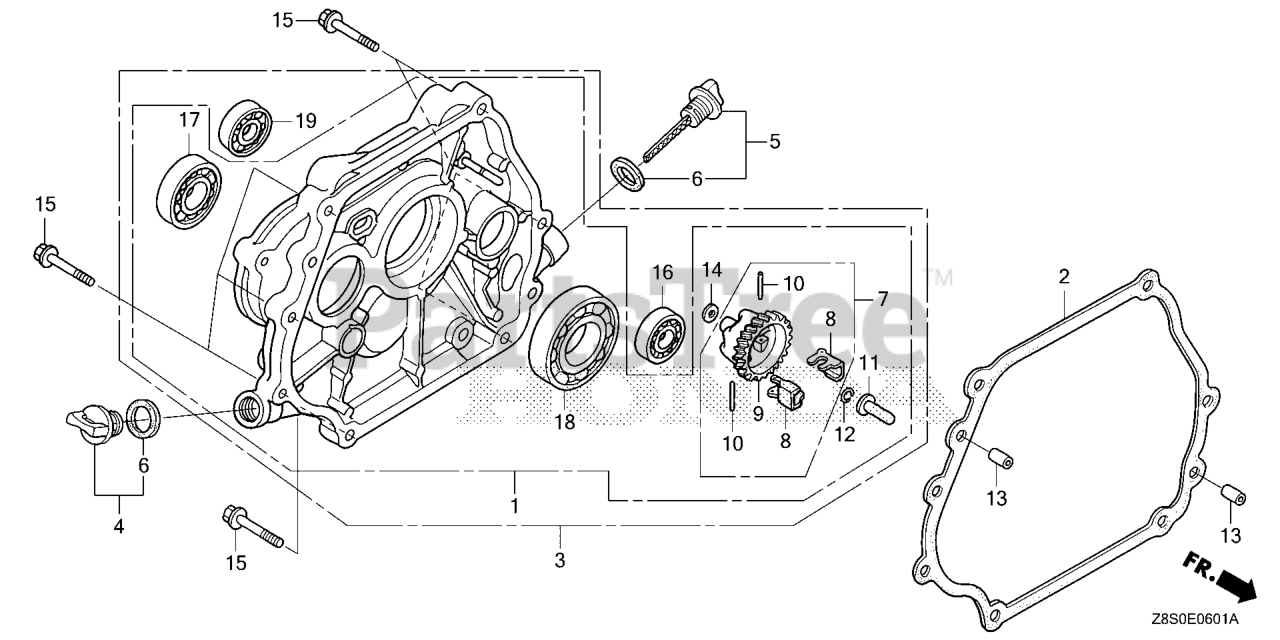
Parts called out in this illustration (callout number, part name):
2	GASKET, CASE COVER
3	COVER ASSY., CRANKCASE
4	CAP ASSY., OIL FILLER
5	CAP ASSY., OIL FILLER
6	GASKET, OIL FILLER CAP
7	GOVERNOR ASSY. (BALANCER)
8	WEIGHT, GOVERNOR
9	HOLDER, GOVERNOR WEIGHT
10	PIN, GOVERNOR WEIGHT
11	SLIDER, GOVERNOR
12	CLIP, GOVERNOR HOLDER
13	PIN, DOWEL (8X12)
14	WASHER, PLAIN (6MM)
15	BOLT, FLANGE (8X35)
16	BEARING, RADIAL BALL (6202)
17	BEARING, RADIAL BALL (6204)
18	BEARING, RADIAL BALL (6206)
19	BEARING, RADIAL BALL (6302)
